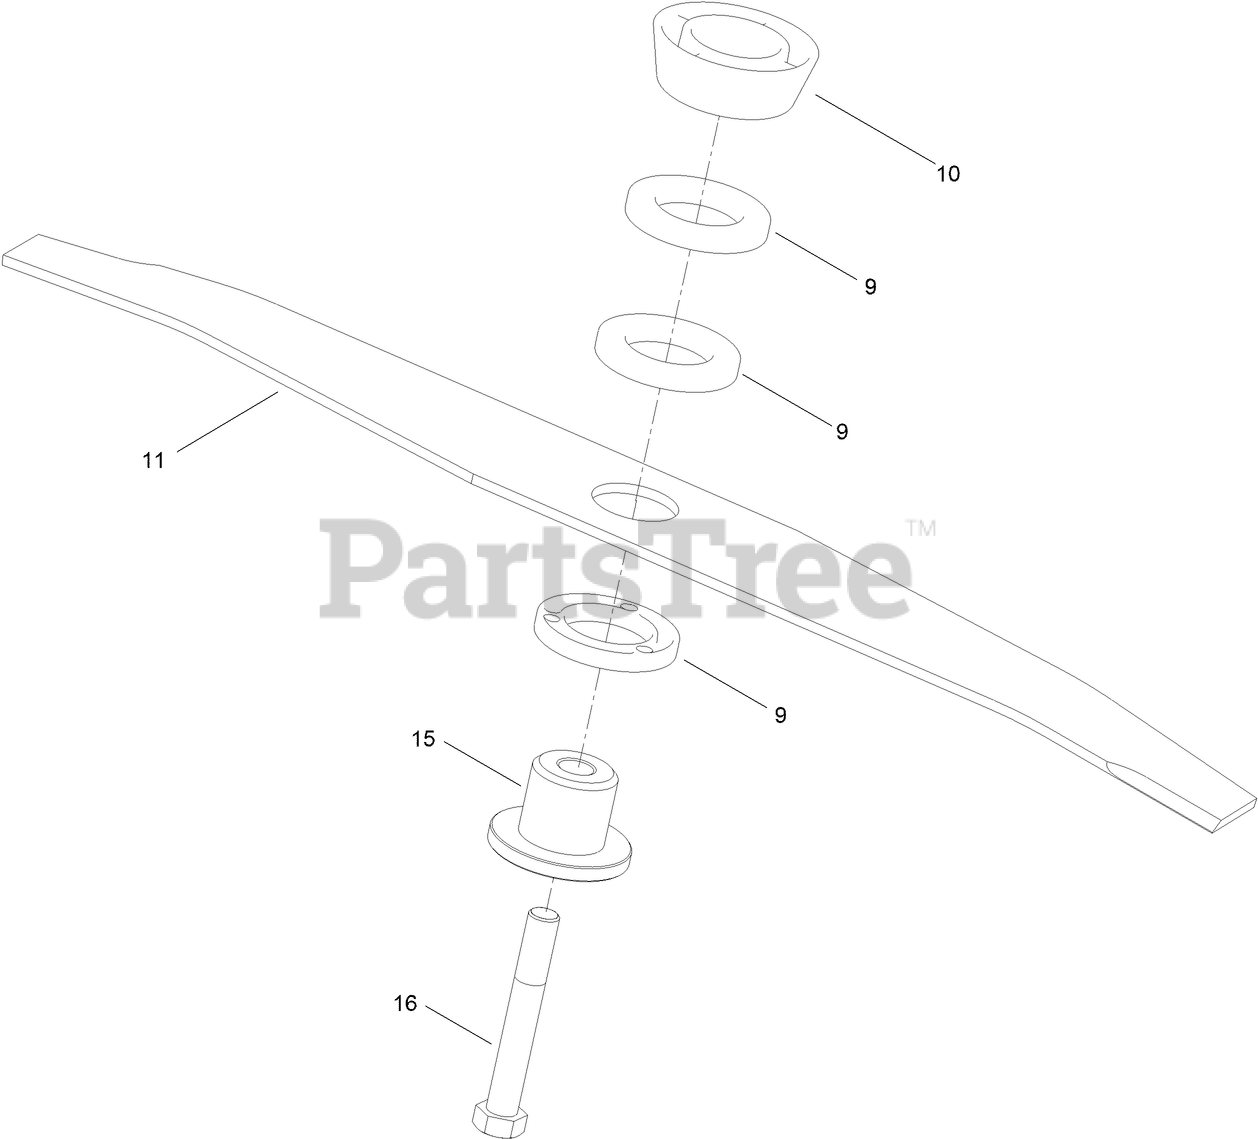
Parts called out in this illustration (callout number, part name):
9	SPACER-BLADE, ALUMINIUM
10	SPACER-DISTANCE
11	BLADE-46 CM
15	RETAINER-BLADE EHOVERPRO
16	BOLT, UNF 7/16 X 3 (GRADE 8, ROHS)
